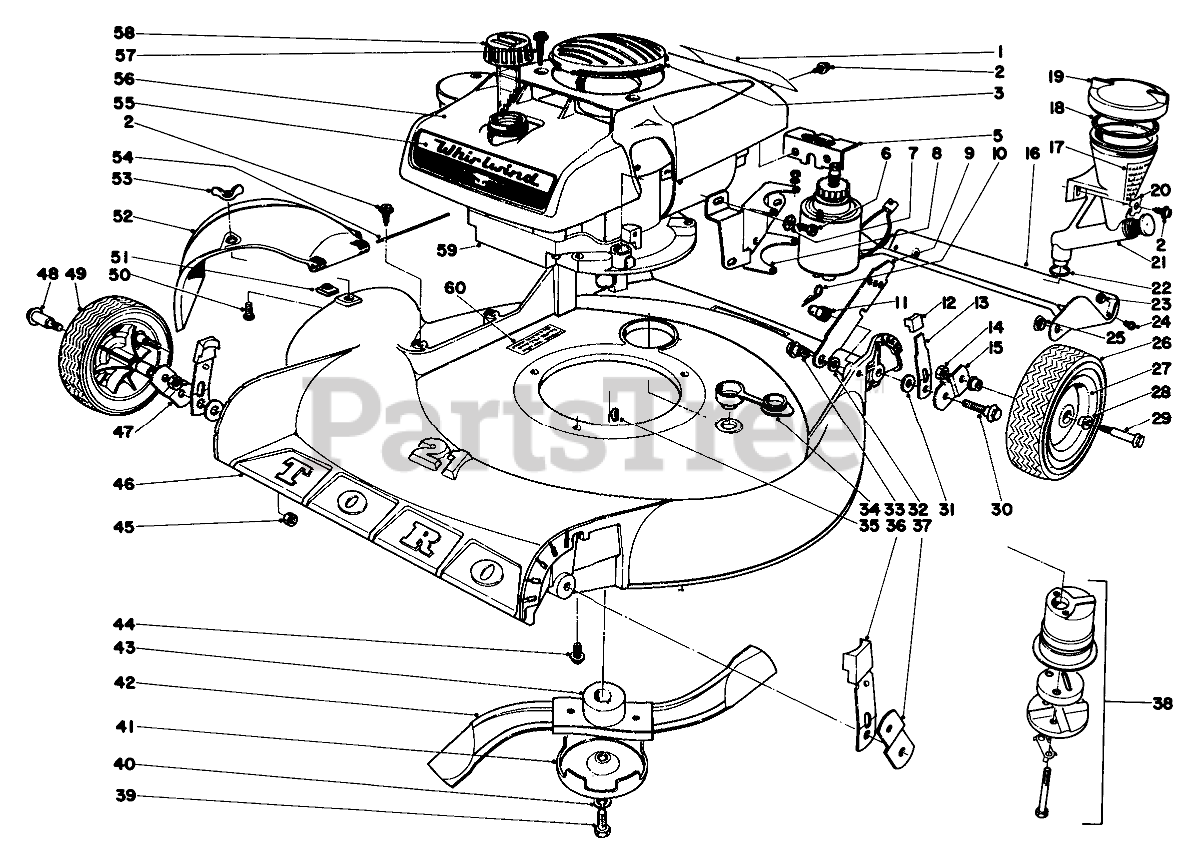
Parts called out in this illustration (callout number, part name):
1	Decal
2	Screw
3	Insert Shroud
5	Bracket
6	SCREW-HH
7	WASHER-FLAT
8	Bracket
9	Latch
10	Hairpin Cotter
11	Nut
13	Spring Arm
14	Nut
15	Pivot Arm
16	Safety Shield-Rear
17	Decal, Reservoir
18	"O" Ring
19	Cap, Reservoir (Incl. Ref. 18)
20	Washer
21	Reservoir, Oil
22	O-RING
23	NUT-JAM
24	Screw-Nylon
25	Nyliner
26	8 TIRE
27	Wheel Assy. (Incl. Ref. 28)
28	Bushing
29	Wheel Bolt
30	Pivot Screw
31	WASHER-PIVOT
32	SPACER
33	SCREW-SHOULDER
34	Washer Plug
35	KEY-WOODRUFF
36	ARM KNOB
37	Pivot Arm
38	MUFFLER KIT
39	SPECIAL SCREW
40	WASHER-LOCK
41	Scalp Cup
42	Blade
43	BLADE RETAINER WA
44	Screw
45	Nut
46	Housing
47	Pivot Arm
51	NUT-SPEED
52	Deflector
53	NUT-WING SPECL
54	HINGE PIN
55	Decal
56	Shroud
57	SCREW-HWH
58	Gas Cap
59	Engine
60	Decal
